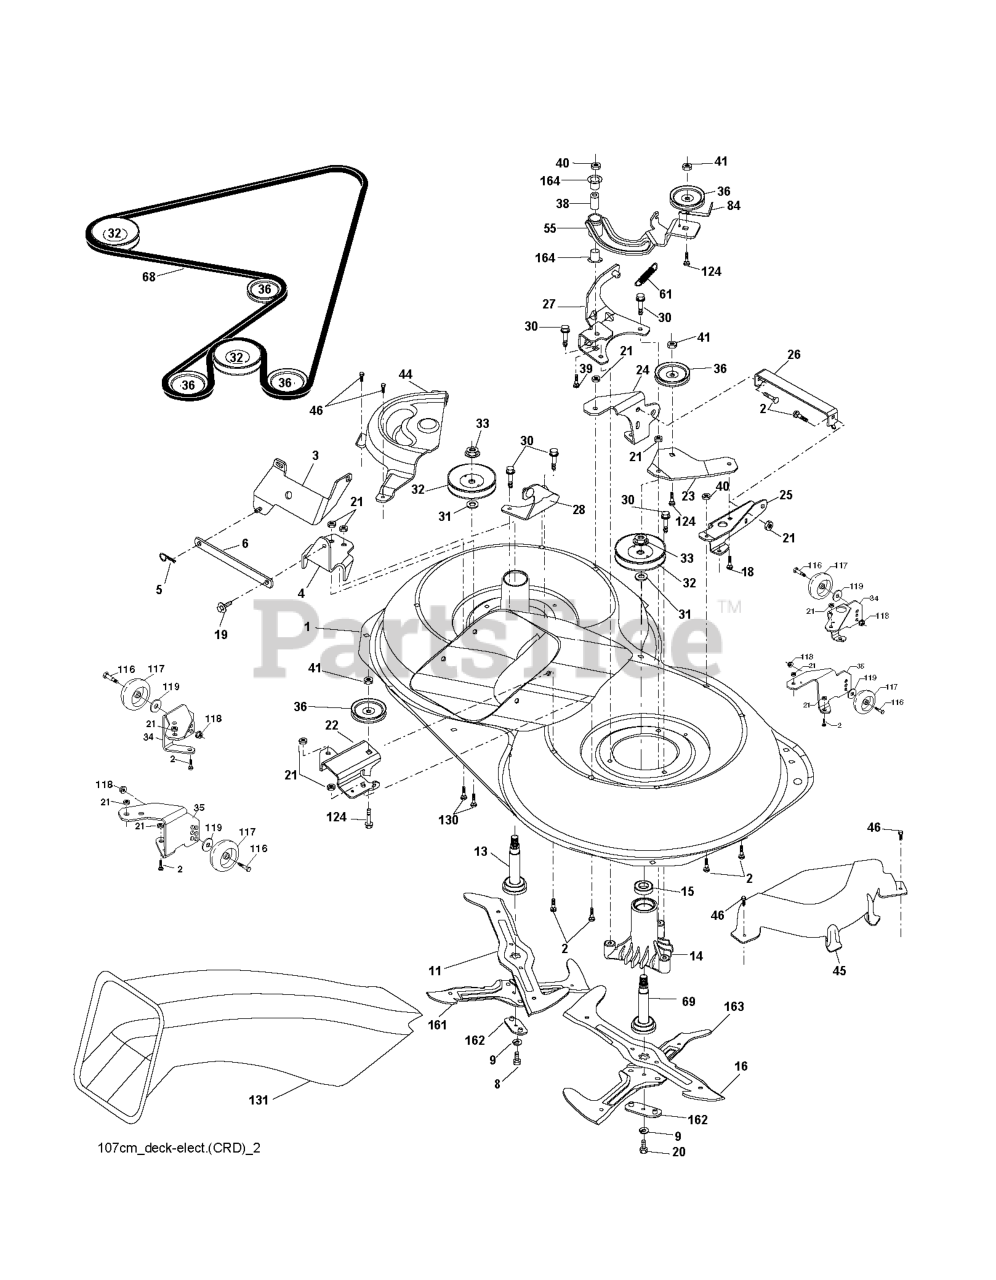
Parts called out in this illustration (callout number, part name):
1	Housing Asm. Mower 107 CRD
2	RP BOLT 5/16-18 X3/4 ZN/YEL GR
5	RETAINER-SPRNG RB
6	BAR.SWAY.92.CRD
8	BOLT.3/8-24X1.25GR8. LHTHRD
9	LOCKWASHER
11	BLADE.3N1.LH.CRD
13	SHAFT ASM VENT
14	HOUSING.MANDREL.VENTED (MACHD)
16	BLADE.3N1.RH.CRD
19	BOLT SHD 5/16-18
20	BOLT.3/8-24X1.25 GR8
21	LOCKNUT
22	BRACKET.IDLER.RR.107.CRD
25	BRACKET RF
26	SUPPORT
28	BRACKET
30	SCREW, WASHER HEAD
31	WASHER.SPACER.MANDREL
32	PULLEY.MANDREL.4.80 PD.2006
33	NUT.FLANGE.LOCK.TOP
34	BRACKET
35	BRACKET
36	PULLEY.IDLER.4.25
41	NUT LOCK FLG 3/8-16 UNC
45	COVER.MANDREL.RH.CRD
46	SCREW.1/4-20X5/8
55	ARM.IDLER.107.CRD
61	SPRING
68	HEX-BELT 107 MOWER
69	SHAFT.ASM.W/LWR.BRG.RH.THREAD
84	KEEPER, BELT IDLER
116	BOLT.SHOULDER.3/8-16X3-5/8.
117	RP WHEEL. GUAGE RALLY
118	NUT LOCK FLG 3/8-16 UNC
119	WASHER
124	BOLT.3/8-16X1.50
130	BOLT.CARR.SQNK.5/16-18UNC.X3/4
131	CHUTE BAGGER
163	BLADE.CROSS.RH.CRD.107
164	BRNG T
